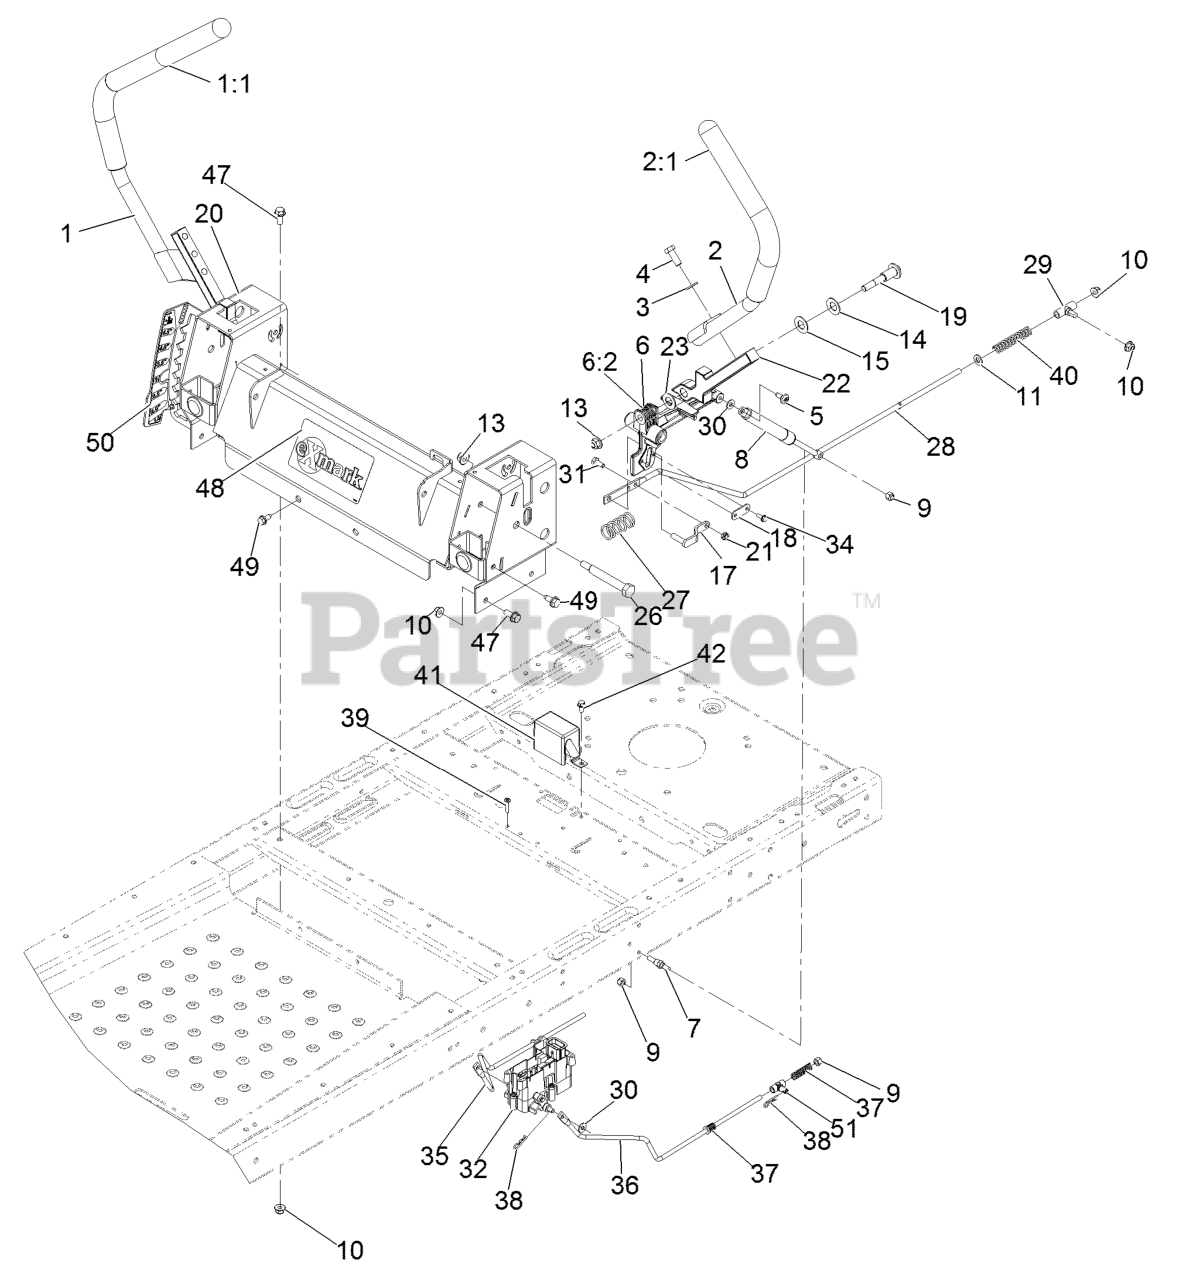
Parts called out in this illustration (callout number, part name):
1	HANDLE-CONTROL, RH
2	HANDLE-CONTROL, LH
3	WASHER-FLAT
4	SCREW-HH
5	SCREW-SHOULDER
6	ACTUATOR ARM ASM
6:2	BUSHING-FLANGE
7	STUD-DAMPER
9	NUT-LOCK, NI
10	NUT-HF, NI
11	WASHER-PLAIN
13	NUT-HF, NI
14	WASHER-BELLEVILLE
18	PLATE-STOP, HYDRO
19	BOLT-PIVOT
20	CONTROL BOX ASM
21	NUT-LOCK, NI
23	WASHER-NYLON
26	BOLT-PIVOT
27	SPRING-RETURN
28	ROD-HYDRO
29	MOUNT-ROD, HYDRO
31	SCREW-HH
34	SCREW-TAPTITE
35	ROD-BRAKE, RH
36	ROD-BRAKE, LH
37	SPRING-COMPRESSION
39	SCREW-PPH
40	SPRING-RETURN, NEUTRAL
41	COVER-BRAKE
42	SCREW-HWH
47	SCREW-HHF
49	Screw-HWH 5/16-18 X 3/4 Tf
50	DECAL-HOC
51	MOUNT-PIVOT
